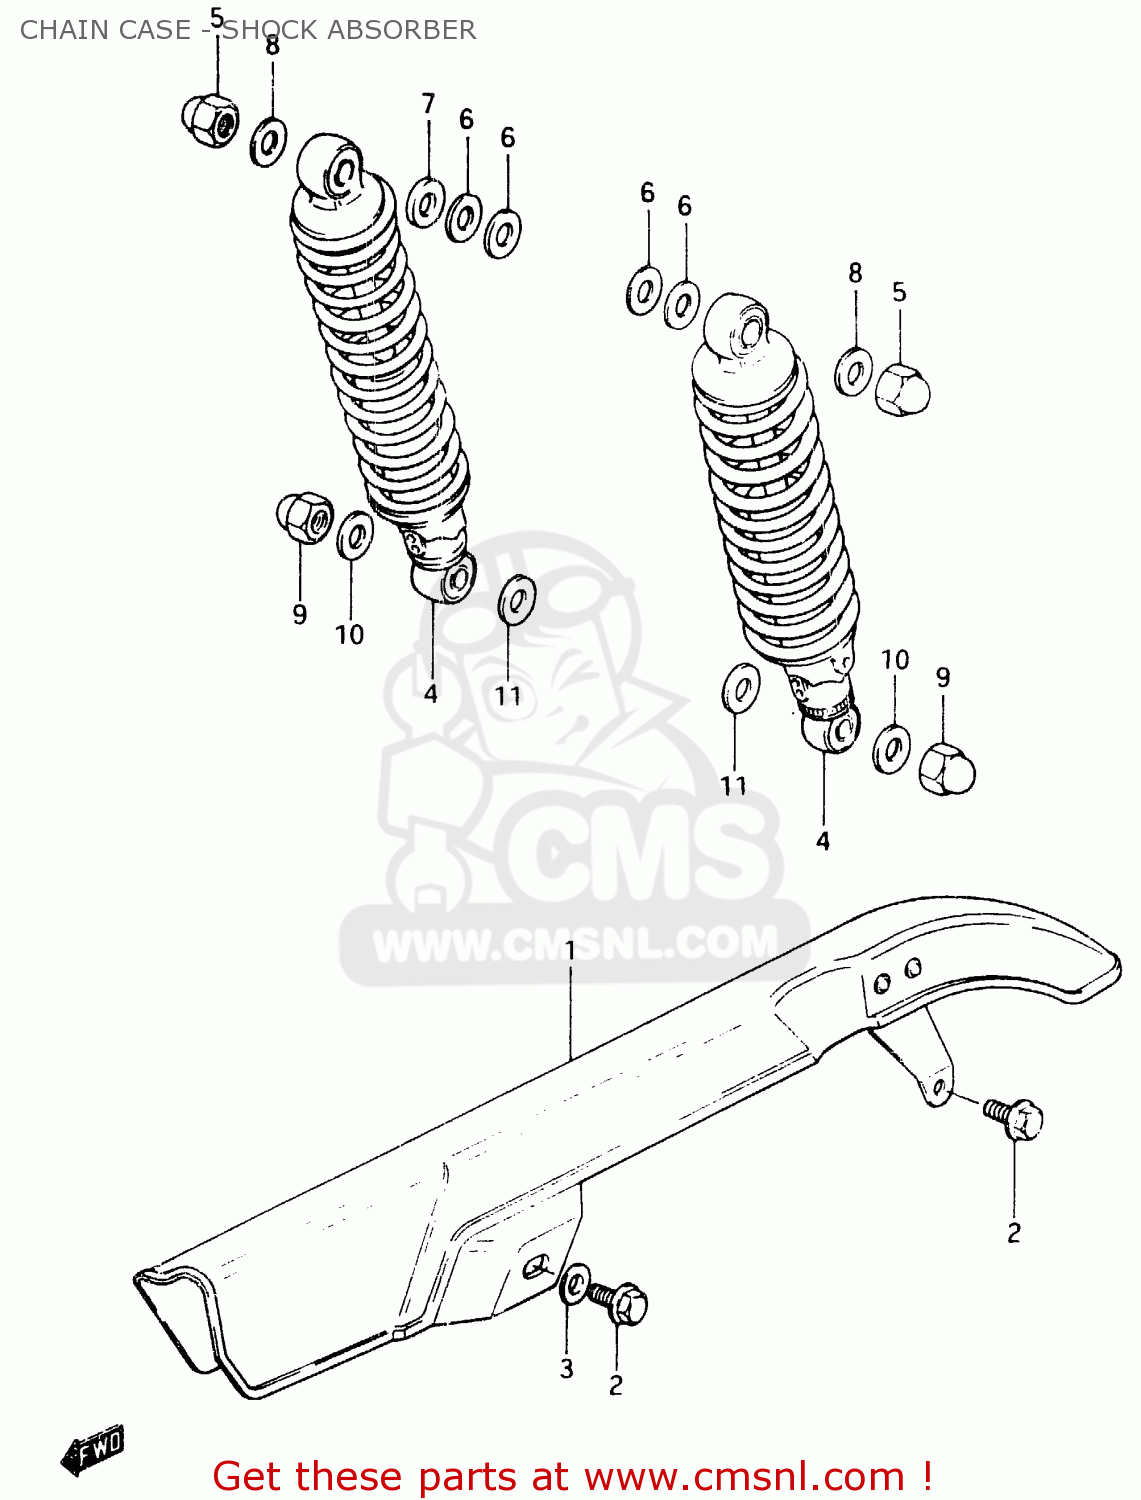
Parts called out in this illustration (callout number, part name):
1	CHAIN CASE
2	BOLT
3	WASHER
4	ABSORBER ASSY,RR SHOCK
5	NUT
6	WASHER
7	WASHER (12.5X24X3.2)
8	WASHER
9	NUT, LOWER LH
10	WASHER
11	WASHER (12.5X24X1.6)
